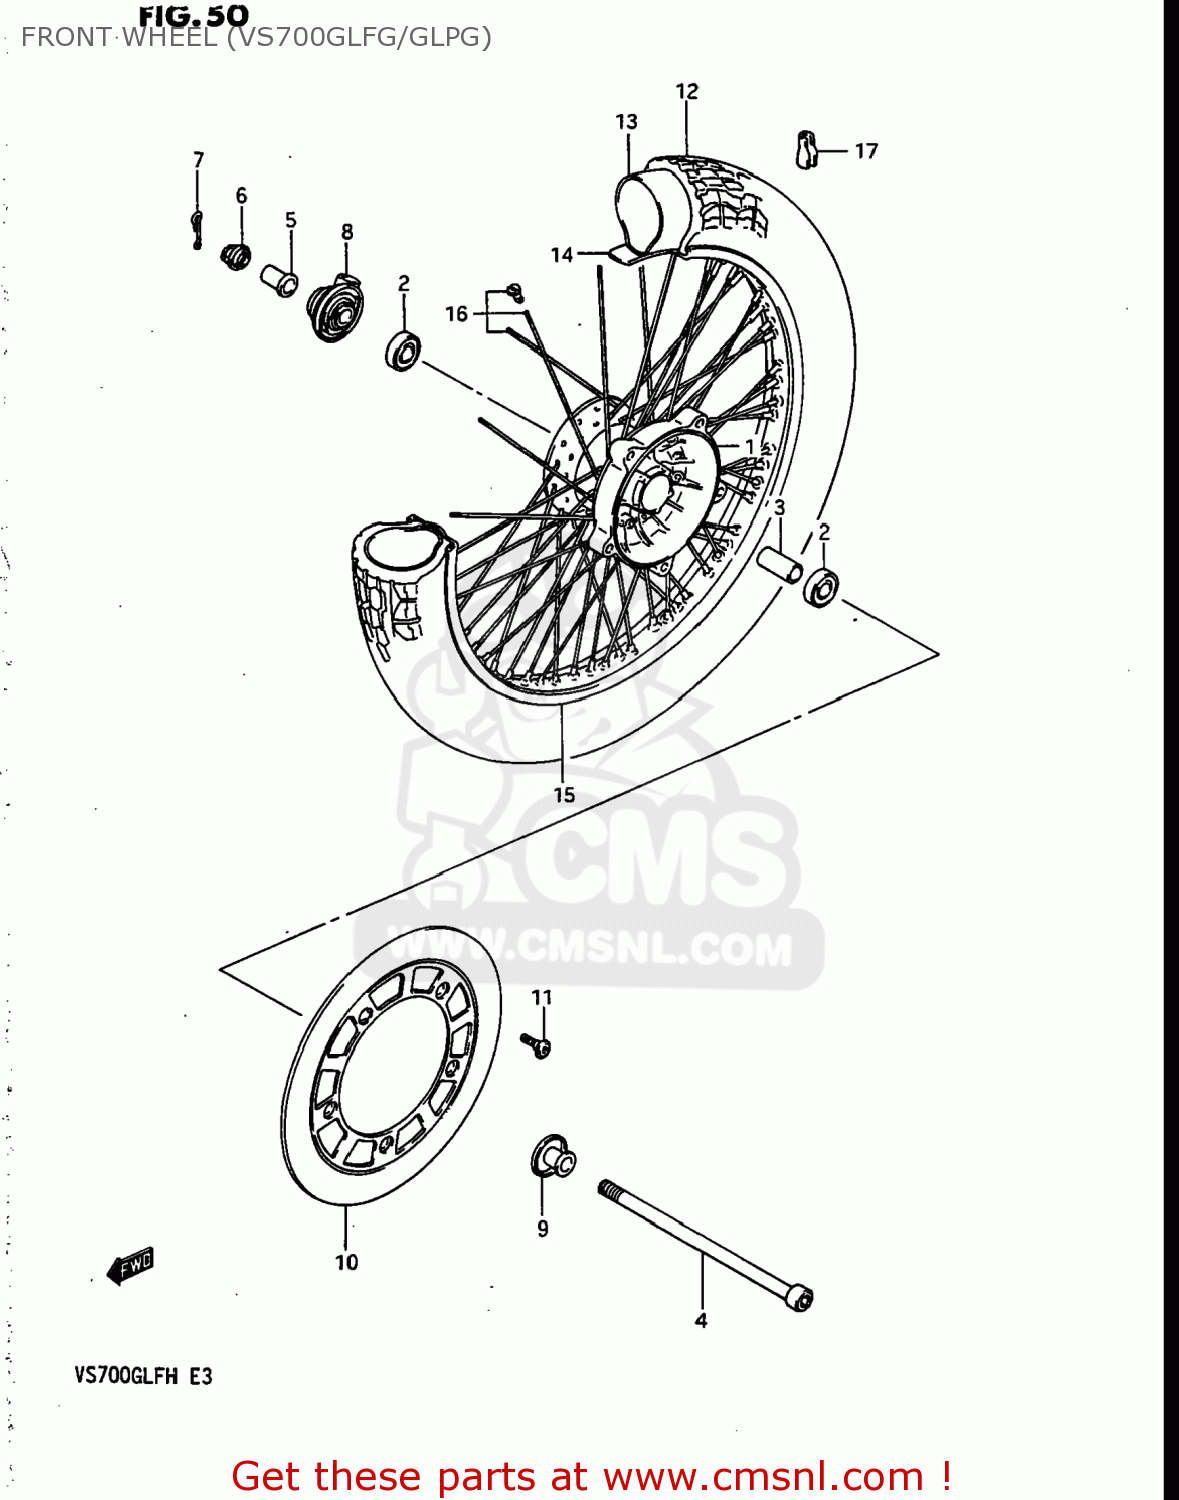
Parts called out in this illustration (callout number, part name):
1	HUB ASSEMBLY,FRONT
2	BEARING
3	SPACER(15.3X21.7X65)
4	AXLE,FRONT
5	SPACER,FRONT AXLE,RIGHT
6	NUT
7	PIN,FRONT AXLE
8	BOX ASSY,SPEEDOMETER GEAR
9	SPACER,FRONT AXLE,LEFT
10	DISC,FR BRAKE
11	BOLT(8X25.5)
12	TIRE,FRONT
13	TUBE,INNER
14	PROTECTOR,WHL INR TUBE
15	RIM,FRONT WHEEL (MT2.15)
16	SPOKE SET,FRONT
17	BALANCER,WHEEL
